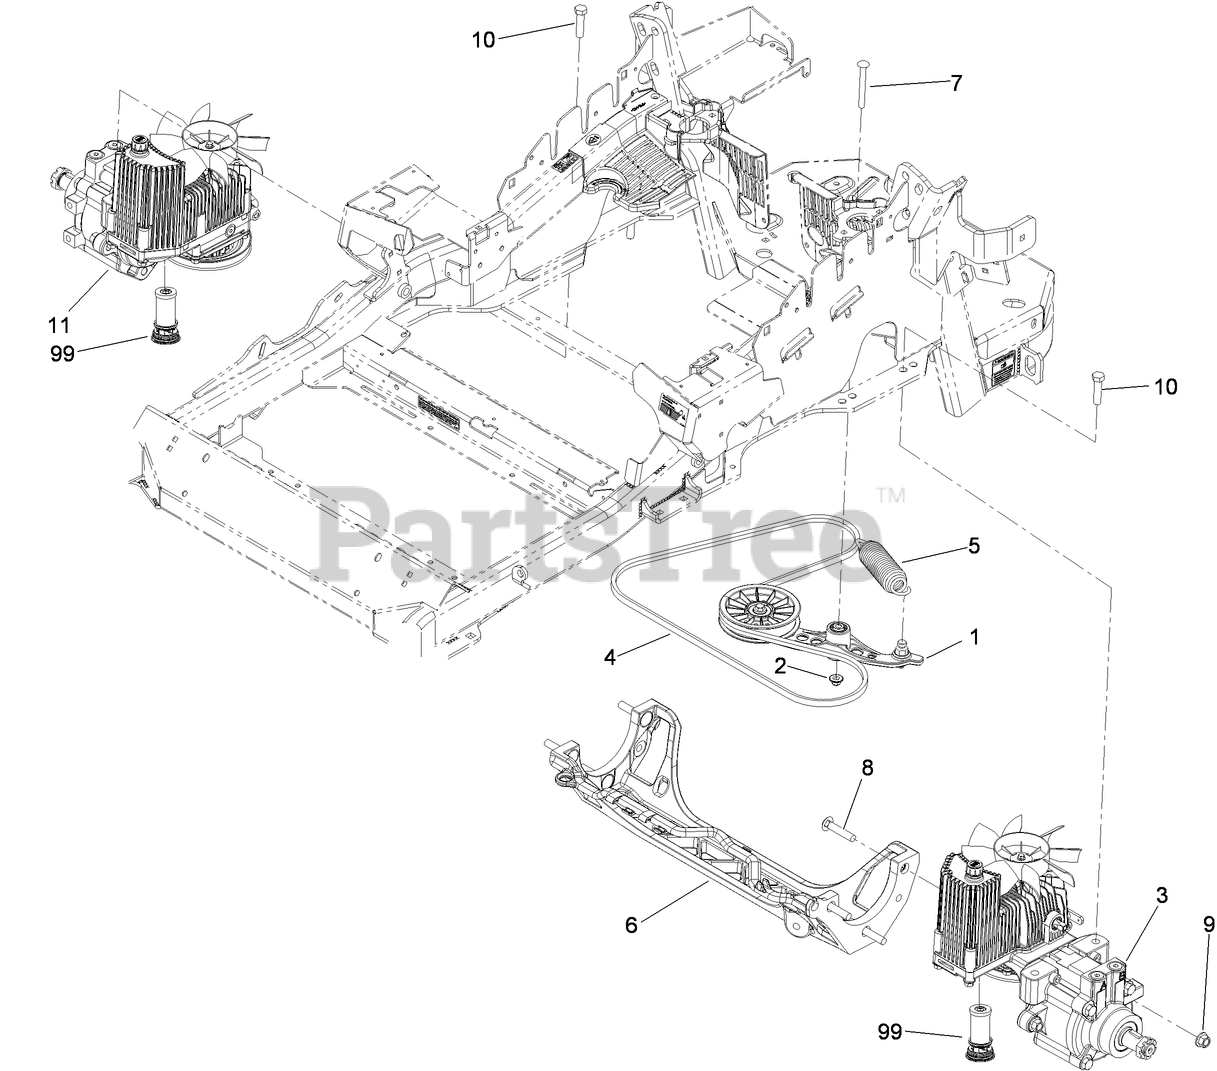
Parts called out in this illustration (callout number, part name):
1	PUMP IDLER ASM
2	NUT-FLANGE, NI
3	LH HYDRO ASM (12cc W/SHOCK)
4	BELT
5	EXTENSION-SPRING
6	CRADLE-HYDRO
7	BOLT-SHOULDER, CARRIAGE
8	SCREW-CARR
9	NUT-LOCK
10	SCREW-HH
11	RH HYDRO ASM (12cc W/SHOCK)
99	FILTER-HYDRO
